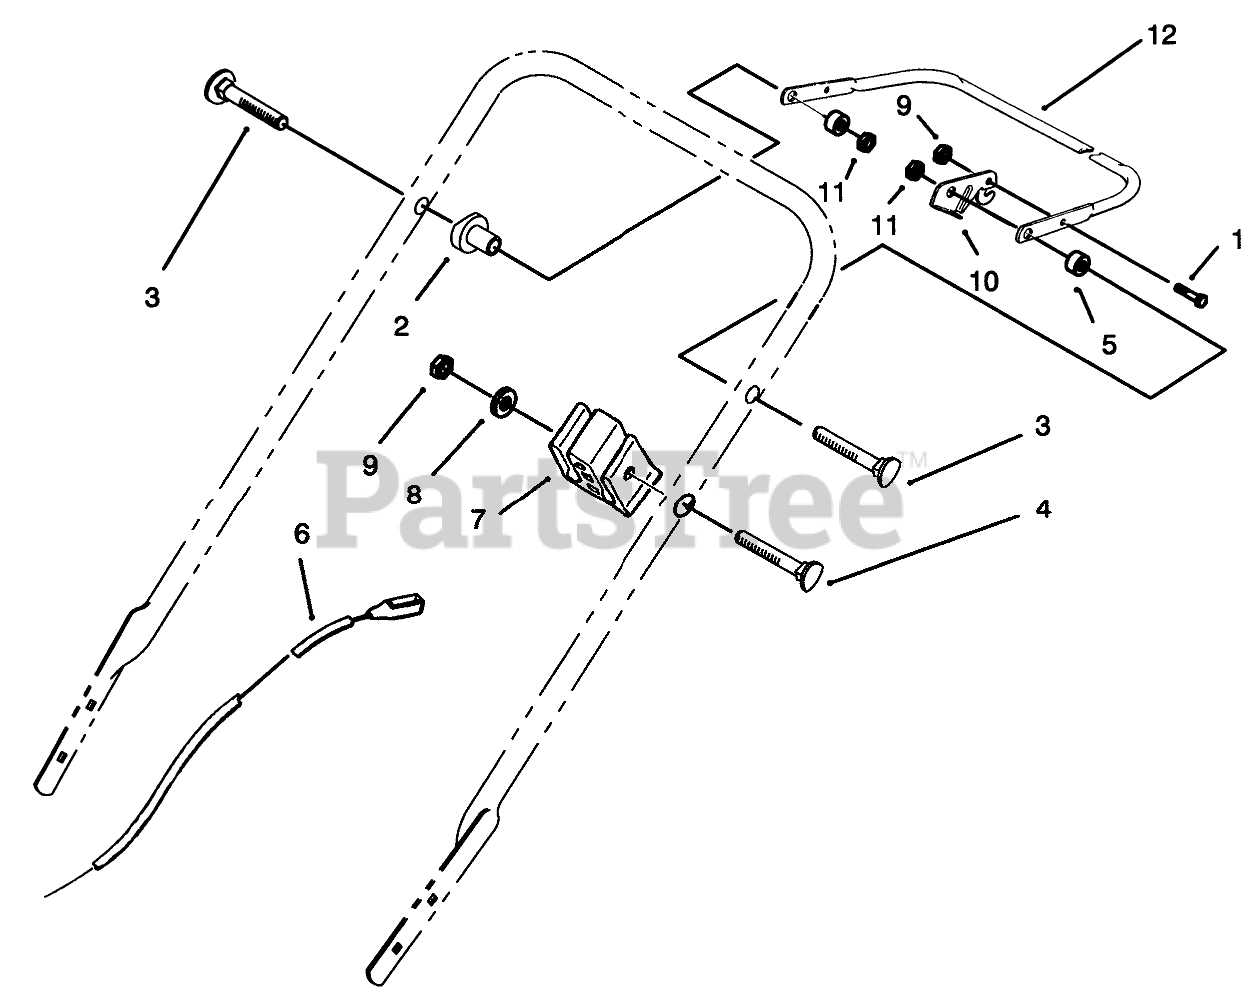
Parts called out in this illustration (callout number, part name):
1	SCREW-HH
2	SPACER-SUPPORT
3	SCREW-HANDLE
4	SCREW-HANDLE
5	SPACER-NYLON
6	BRAKE CONTROL
7	SUPPORT-CABLE
8	WASHER-FLAT
9	NUT-LOCK, NI
10	Lever-Control
11	NUT-LOCK NI
12	Bar-Control
